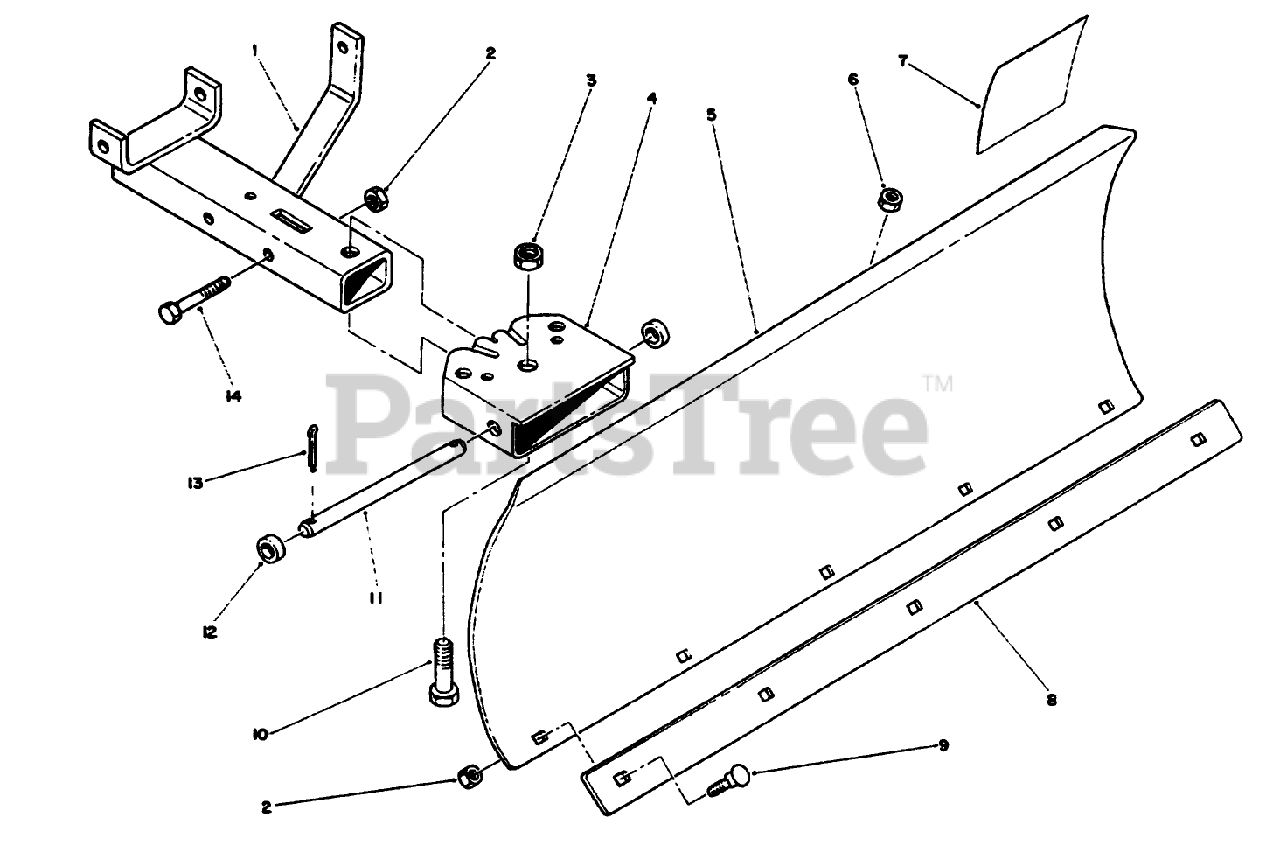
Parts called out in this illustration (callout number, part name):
1	Frame
2	NUT-LOCK, NI
3	NUT-LOCK, NI
4	ASS'Y-QUADRANT R
5	Blade
6	NUT-JAM
7	DECAL - DANGER
8	Plate
9	SCREW-CARR
10	SCREW-HH
11	10-522-05 TECOMASTE
12	Spacer
13	PIN-COTTER
14	SCREW-HH
